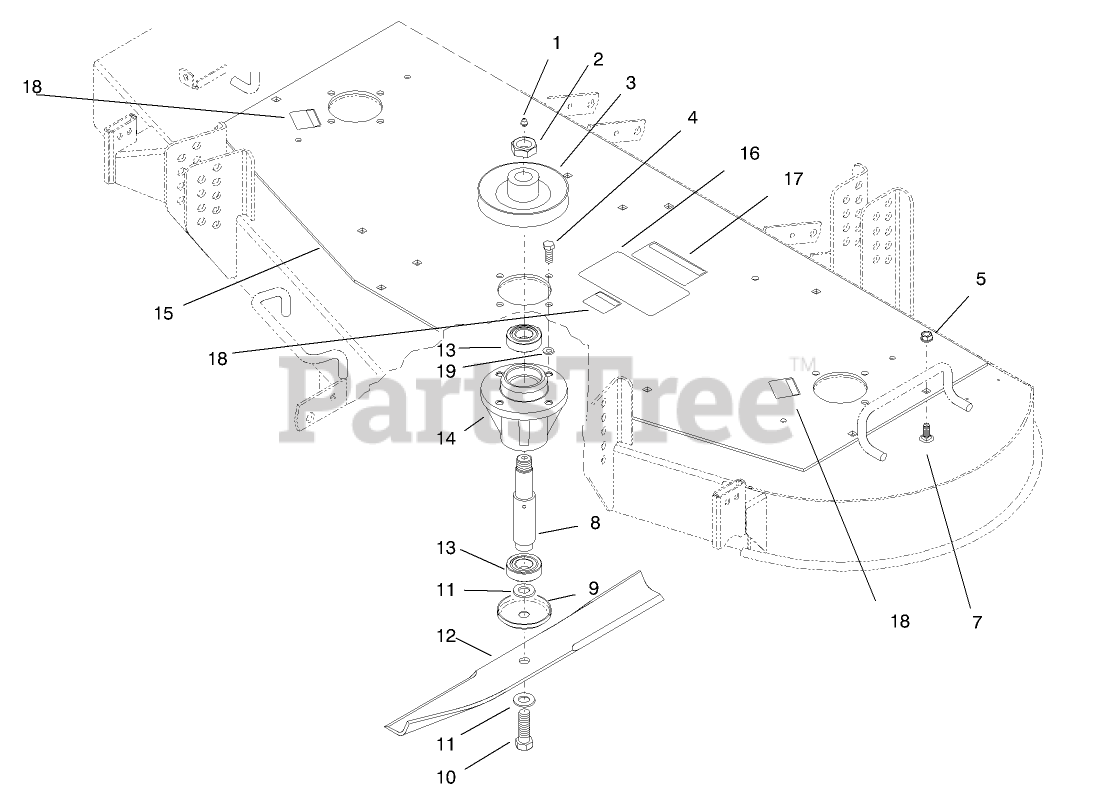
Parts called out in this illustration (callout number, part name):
1	FITTING-GREASE
2	NUT-LOCK, NI
3	PULLEY - SPINDLE BLACK
4	SCREW-HH, LOCK
5	NUT-LOCK, NI
7	BOLT-CARR
8	SHAFT - SPINDLE
9	CUP-SPINDLE
10	SCREW-HH
11	WASHER-SPECIAL
12	BLADE
13	BEARING-BALL
14	HOUSING - SPINDLE
15	Plate-Top
15	ASM - TOP PLATE W/DECALS
16	DECAL - BELT INSTALLATION
17	DECAL-TORQUE
18	DECAL-WARNING
19	WASHER-FLAT
